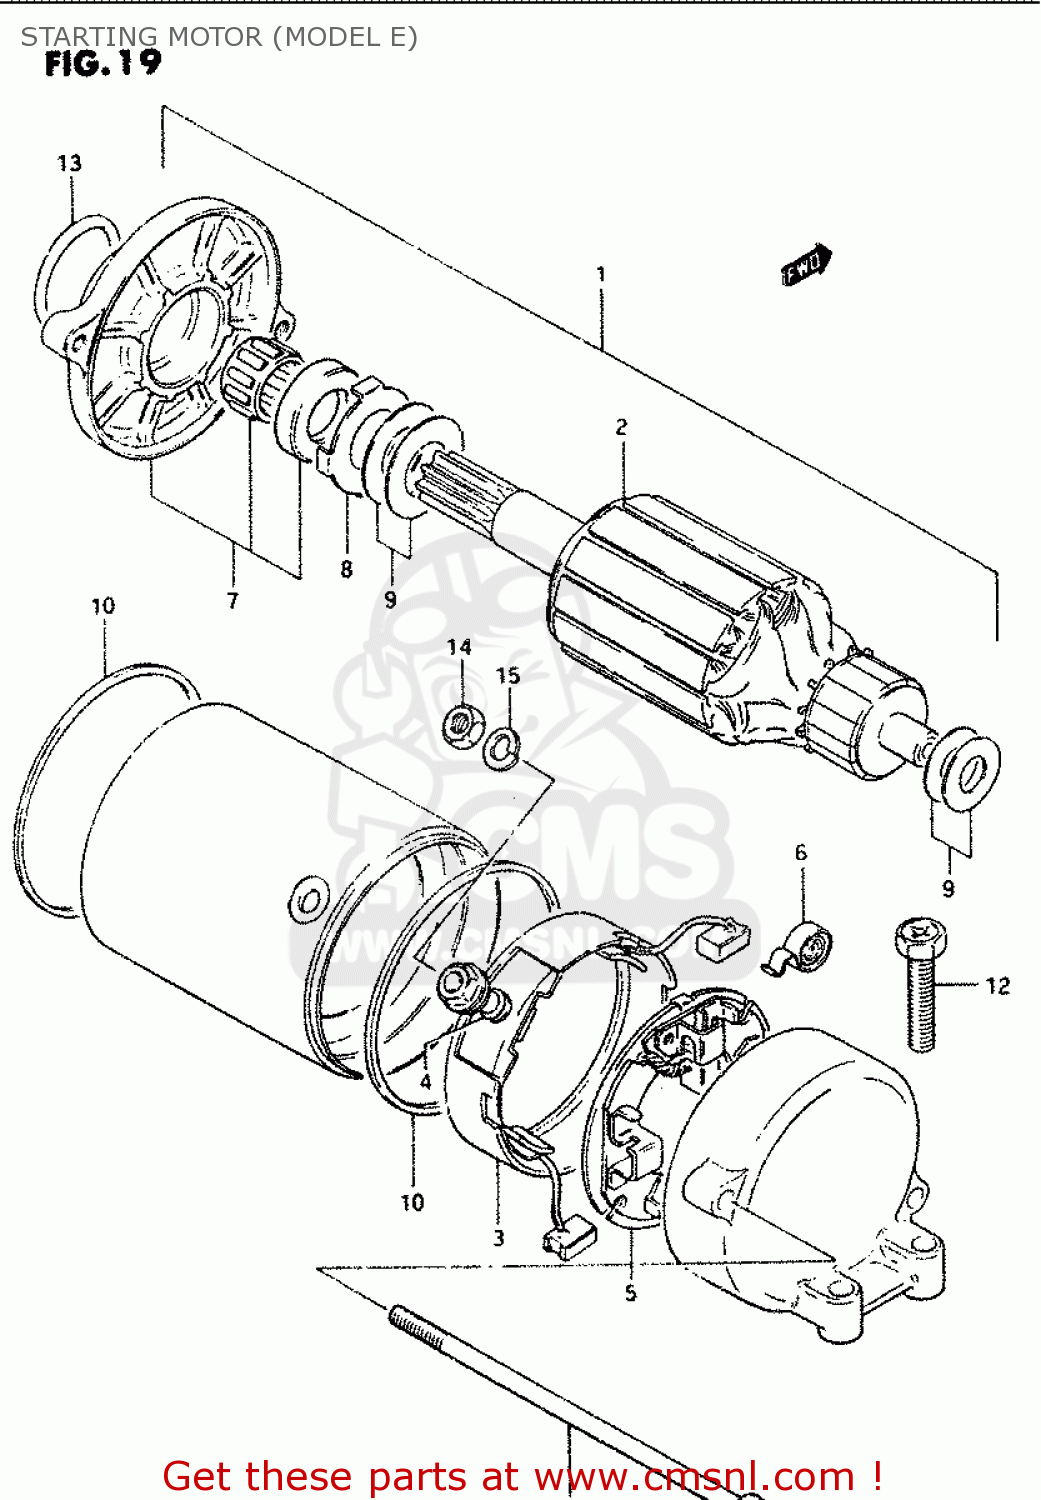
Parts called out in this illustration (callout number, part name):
1	MOTOR ASSEMBLY,STARTING
2	ARMATURE
3	BRUSH TERMINAL SET (+)
4	O RING
5	HOLDER,BRUSH
6	SPRING,BRUSH
7	HOUSING SET,STARTING MOTOR
8	SHIM SET
9	SHIM SET
10	SEAL,RING
11	BOLT,STARTING MOTOR HOUSING
12	SCREW (6X25)
13	O RING(D:3,ID:24.5)
14	NUT
15	WASHER,LOCK
